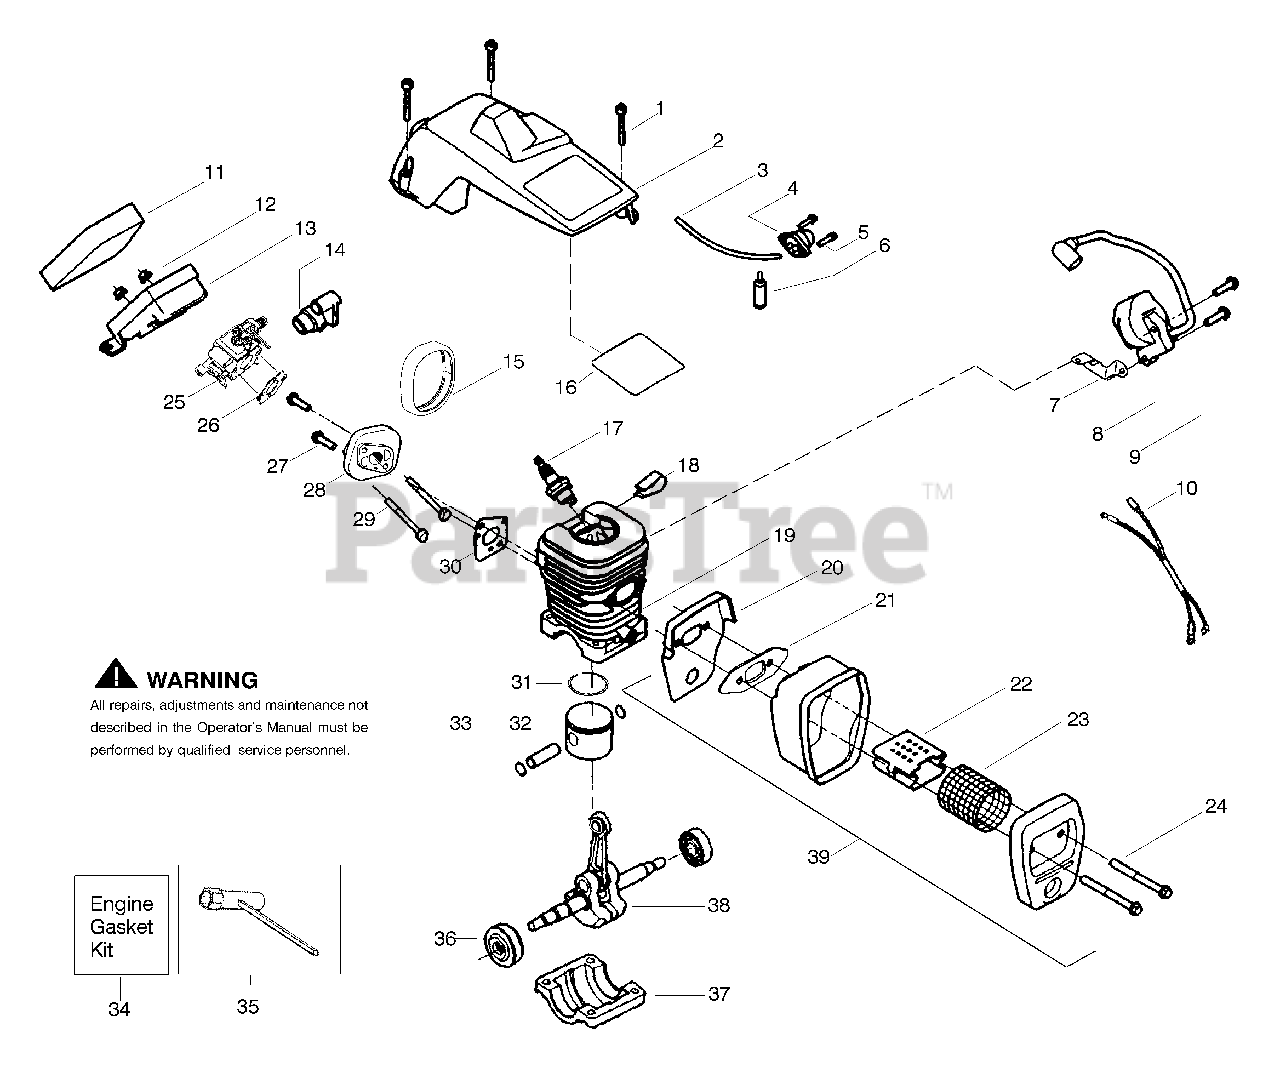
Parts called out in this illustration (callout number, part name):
2	Assy Cylinder Shield
3	Kit Fuel Line (Small)
4	Assy Air Purge
6	Assy Fuel Pick up
7	Strap Ground
8	Ignition Module
10	Assy Wire Harness
11	Foam Air Filter
13	Assy Air Box
14	Grommet Carb Adjust
15	Seal Carb Adapter
16	Reflector Heat
17	Spark Plug (RCJ 7Y)
18	Clip High Tension Lead
19	Cylinder
20	Backplate Muffler
21	Gasket Muffler(kit)
22	Diffuser Muffler
23	Screen Spark
24	Bolt Muffler
25	Kit Carburetor Zama (W20)
25	Kit Carburetor Walbro (WT662)
26	Gasket Carb. (kit)
28	Carb. Adapter
30	Gasket Adaptor(kit)
31	Ring Piston
32	Retainer Piston Pin
33	Kit Piston
34	Kit Engine Gasket
35	Bar Wrench
36	Assy Seal & Bearing
37	Cap Crankcase
38	Assy Crankshaft
39	Assy Muffler
